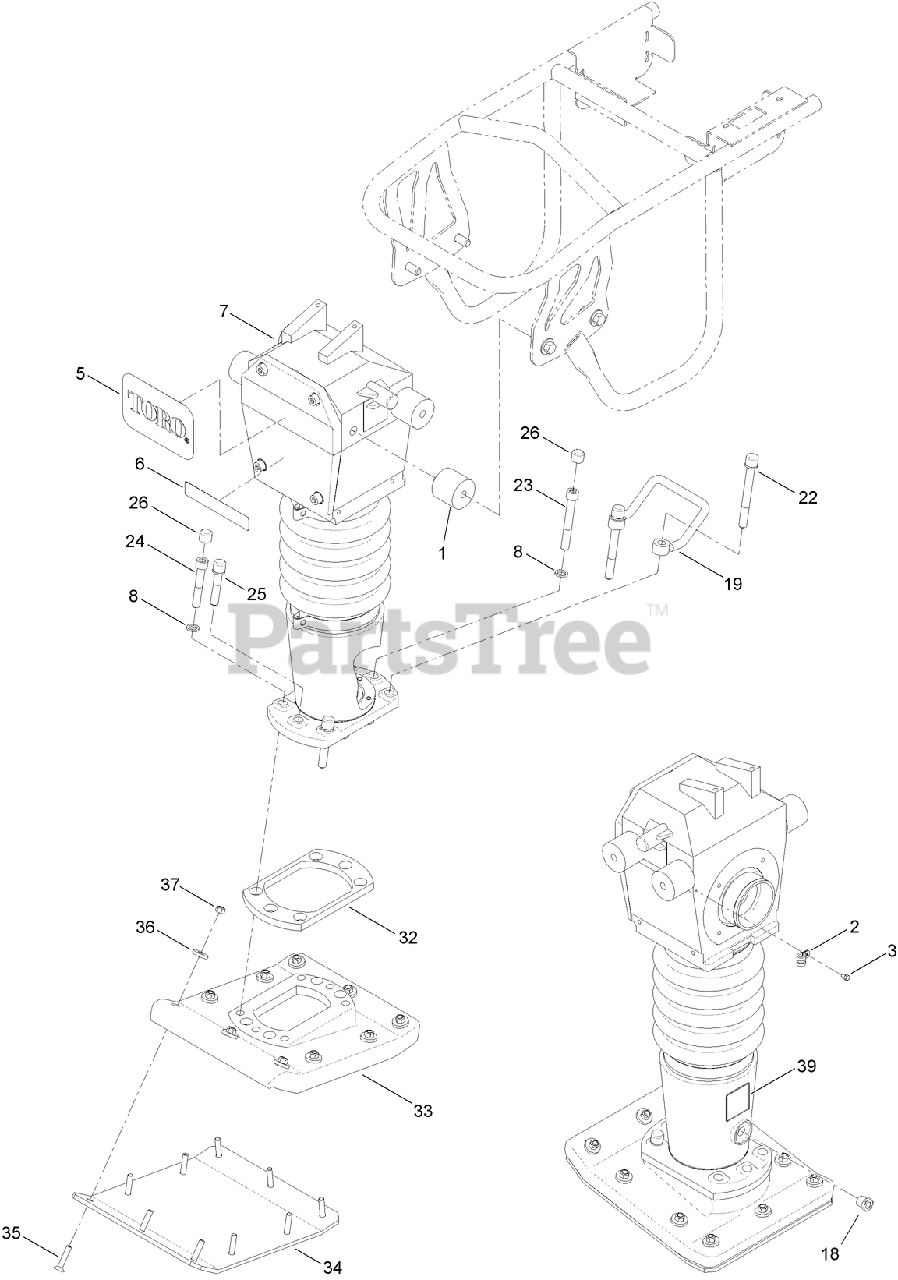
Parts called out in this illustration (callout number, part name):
1	MOUNT-SHOCK
2	CLAMP
3	SCREW-HH
7	RAMMER ASM
8	WASHER-LOCK
18	PLUG-SIGHT, OIL
19	GRIP-LIFT
22	SCREW-HSH
23	SCREW-HSH
24	SCREW-HSH
25	SCREW-HSH
26	CAP-PLASTIC
32	PLATE-SPACER, SHOE
34	PLATE-SHOE
35	SCREW-HSFH
36	WASHER-FLAT
37	NUT-LOCK, NI
39	DECAL-OIL LEVEL
